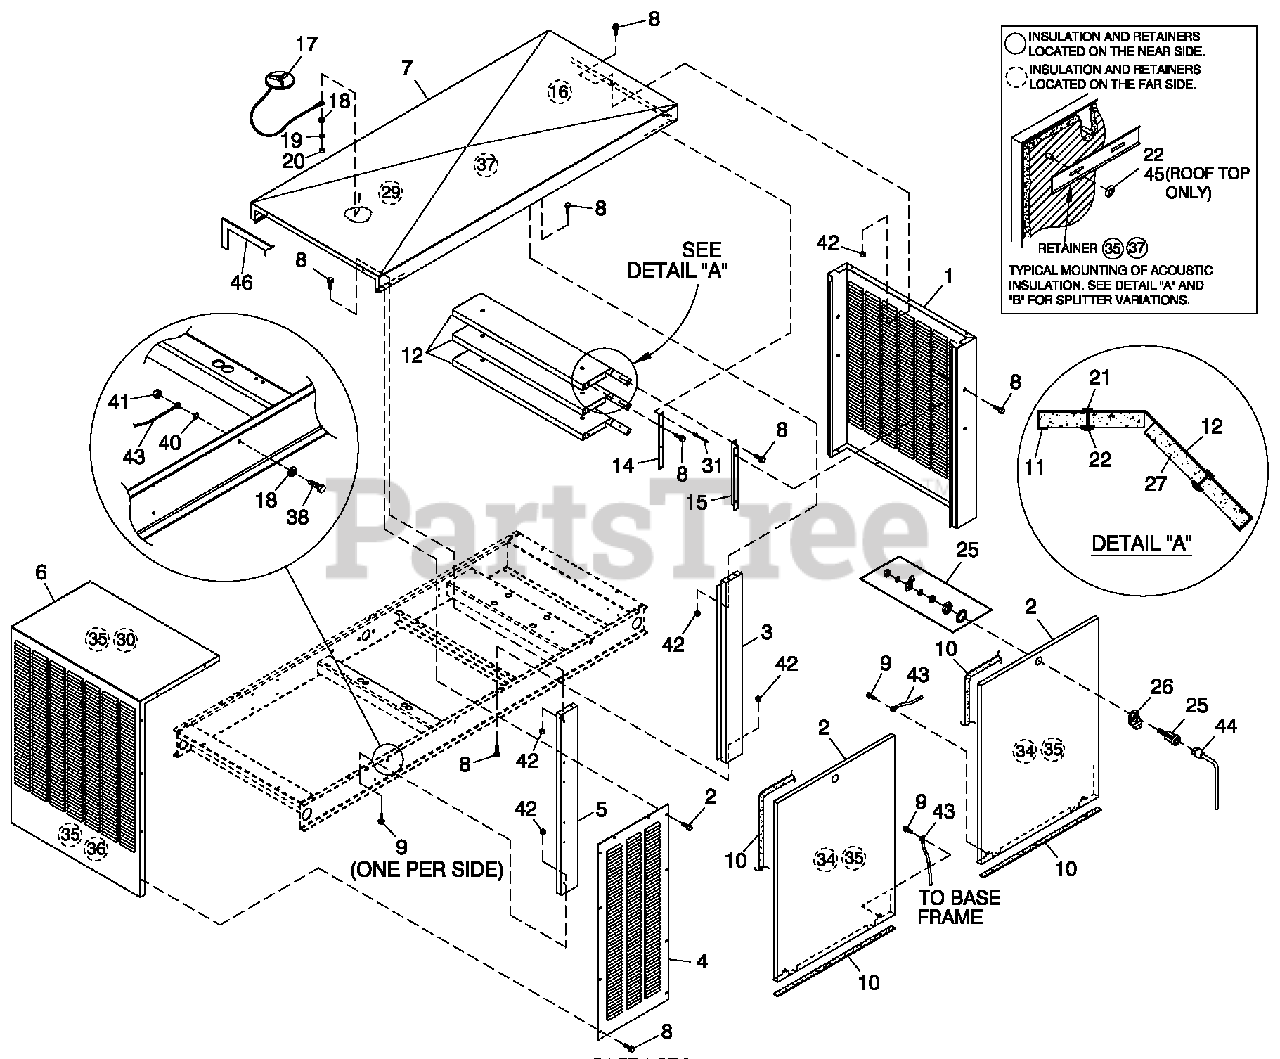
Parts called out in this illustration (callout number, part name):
1	REAR WRAP C3
2	DOOR C3
3	CENTER SUPPORT C3
4	DISCHARGE DUCT LH & RH SIDE C3
5	FRONT CORNERS C3
6	DISCHARGE CENTER DUCT C3
7	ROOF C3 ALUM
8	SCREW THF M6-1 X 16 N WA Z/JS
9	SCREW TH-FRM M6 W/CAP SHKPRF W
10	GASKET EXTRUDED TRIM (547" LG)
11	INSULATION SPLITTER SML
12	SPLITTER
14	STRINGER SPLITTER C3
15	SUPPORT SPLITTER C5 130KW
16	INSULATION ROOFTOP REAR
17	ASSEMBLY COVER ACCESS
18	WASHER FLAT 1/4-M6 ZINC
19	WASHER LOCK M6-1/4
20	NUT HEX 1/4-20 STEEL
21	INSULATION RETAINMENT HANGER
22	WASHER SELF LOCKING DOME #4-40
25	VISE-ACTION LATCH SLOTTED CIR
26	TAB PULL
27	INSULATION SPLITTER
29	INSULATION ROOFTOP
30	INSULATION DUCT TOP
31	RIVET POP .1875 X .450 SS
32	SPLITTER EXTENDED LENGTH
33	INSULATION SPLITTER EXTENDED LENGTH
34	INSULATION DOOR
35	RETAINER INSULATION (820)
36	INSULATION DUCT FRONT
37	RETAINER INSULATION (740)
38	SCREW HHC M6-1.0X20G8.8
40	WASHER SHAKEPROOFINT1/4
41	NUT HEXM6X1.0G8YEL CHR
42	NUT HEX LOCK M6-1.0 SS NY INS
43	ASSY WIRE 14 AWG 34.8" GRN/YEL
44	KEY VISE-ACTION LATCH SLOT CIR
45	WASHER SELF LOCKING DOME #8-32
46	STRIP SEALANT 1/8 X 1 (44.52"LG)
